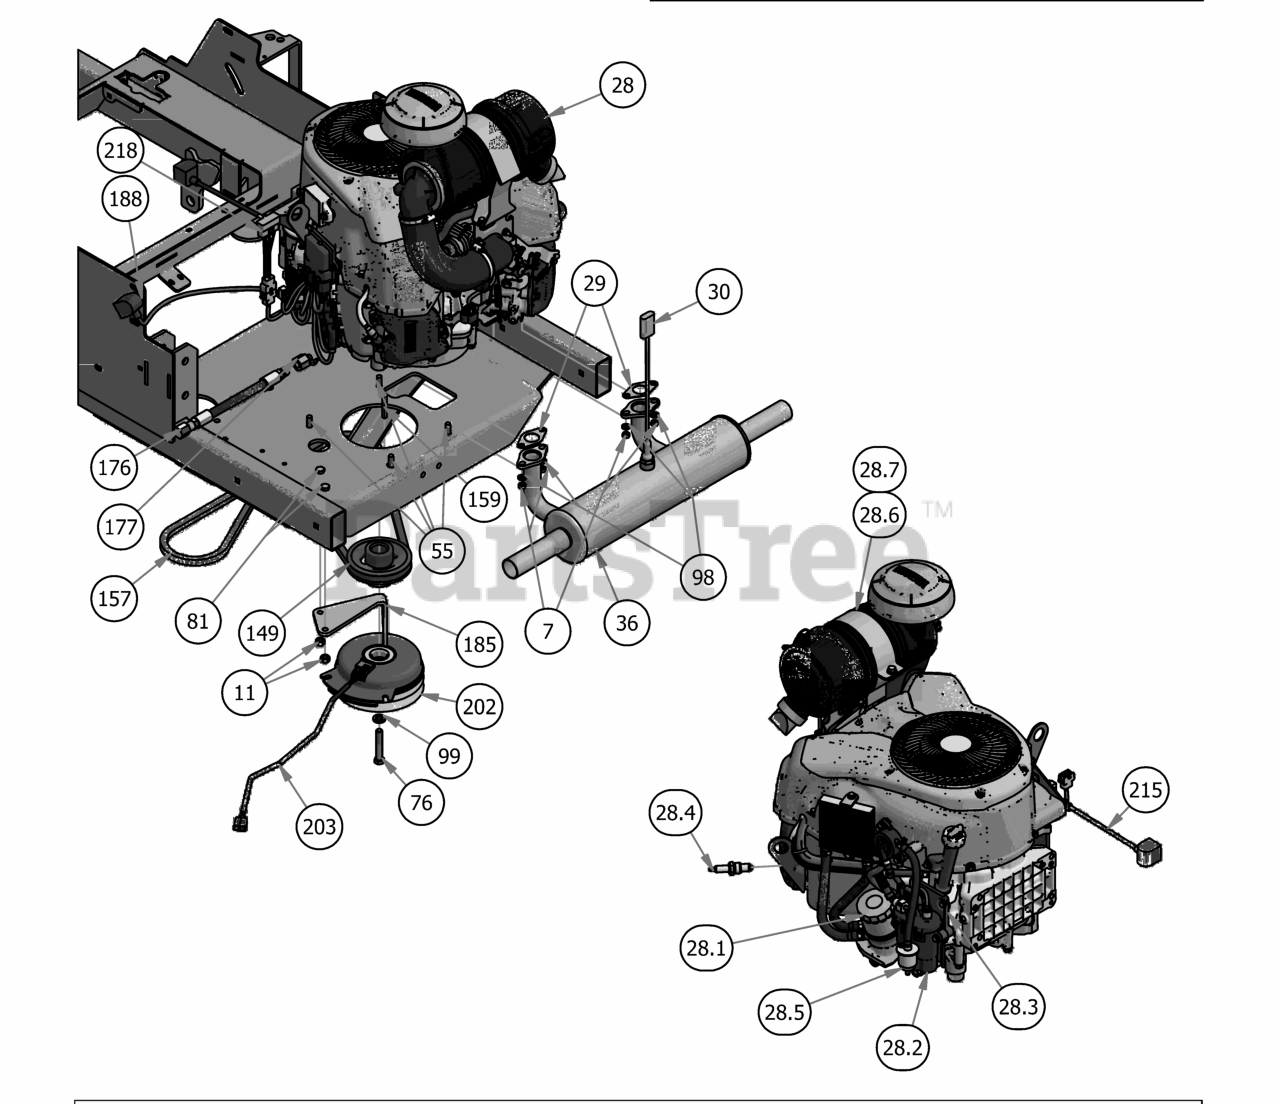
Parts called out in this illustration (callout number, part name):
7	M8-1.25 Zinc Nut
11	3/8" Hex Nut
28	Yamaha 33hp EFI Engine
28.1	Oil Filter
28.2	Yamaha Fuel Pump
28.3	Yamaha Fuel Pump Bracket
28.4	Yamaha Spark Plug
28.5	Yamaha Fuel Filter
28.6	Canister Air Filter- Outer
28.7	Canister Air Filter- Inner
29	Exhaust Gasket for yamaha
30	O2 Sensor for Yamaha
36	Muffler for 27Hp Yamaha
55	3/8 x 1 1/8 bolt
76	7/16" x 2 1/2" Hex Bolt
81	3/8" x 1" Hex Bolt
98	5/16" Lock Washer
99	7/16" Lock Washer
149	4 3/4 Motor Pulley
157	2019 Rogue Pump Belt 68"
159	1/4 x 2 Square key Stock
176	Oil drain Hose for Yamaha
177	Oil Drain Adapter for Yamaha
185	PTO Engager Holder
188	24" Red Battery Cable
202	Clutch Assembly
203	Clutch Pigtail
204	2019 Veritical Suspension Frame
215	Starter Cable
218	2019 Harness Adaptor - Vanguard 37 EFI Vert/Horiz
